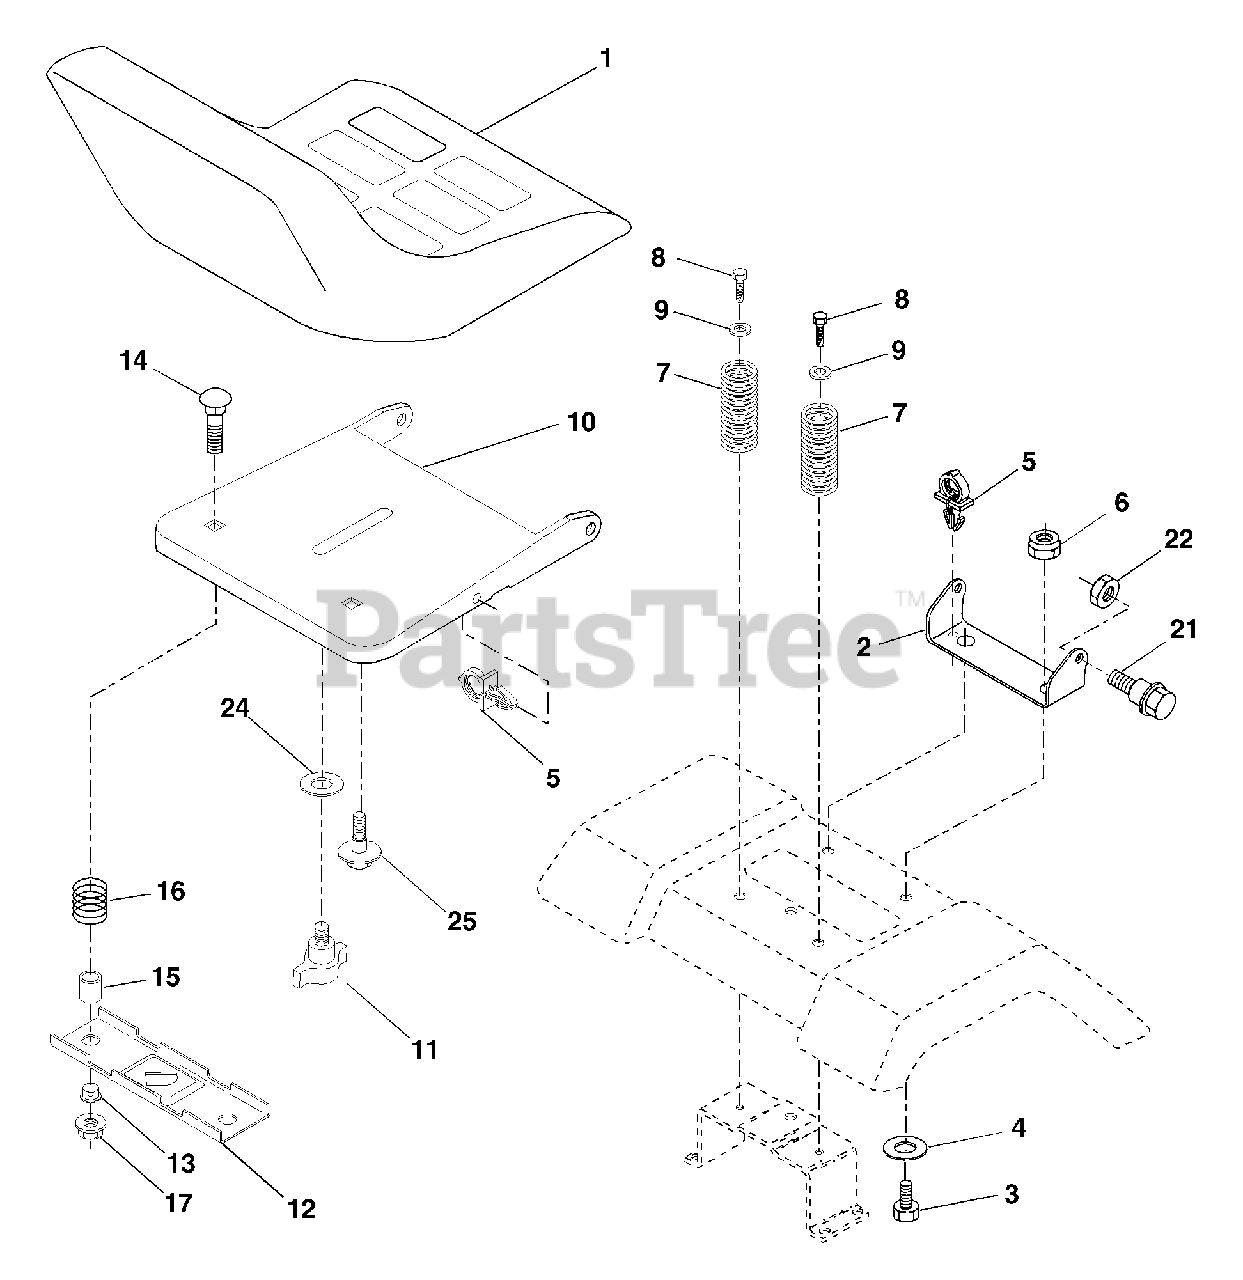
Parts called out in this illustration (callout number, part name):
1	Seat
2	Bracket Pnt Pivot Seat (blk)
3	Bolt
4	Washer 13/32 x 1 x 10 Ga
5	Clip Push-In Hinged
6	Nut
7	Spring Seat Cprsn 2 250 Blk Zi
8	Screw 3/8-16 x 1.5
9	Washer 13/32 x 1 x 14 Ga
10	Pan Pnt Seat (blk)
11	Knob
12	Bracket Pnt Mounting Switch
13	Bushing Snap Blk Nyl 50 Id
14	Bolt Rdhd Sht Nk 1/4-20 x 1-1/2
15	Spacer Split 28 x 96 Yel Zinc
16	Spring Cprsn 1 27 Blk Pnt
17	Nut Lock 1/4 Lge Flg Gr 5 Zinc
21	Bolt Shoulder 5/16-18 Unc Blkz-2A
22	Nut
23	Bolt Hex Black
24	Washer 17/32 x 1-3/16 x 12 Ga
25	Bolt Shoulder 5/16-18 x 62
